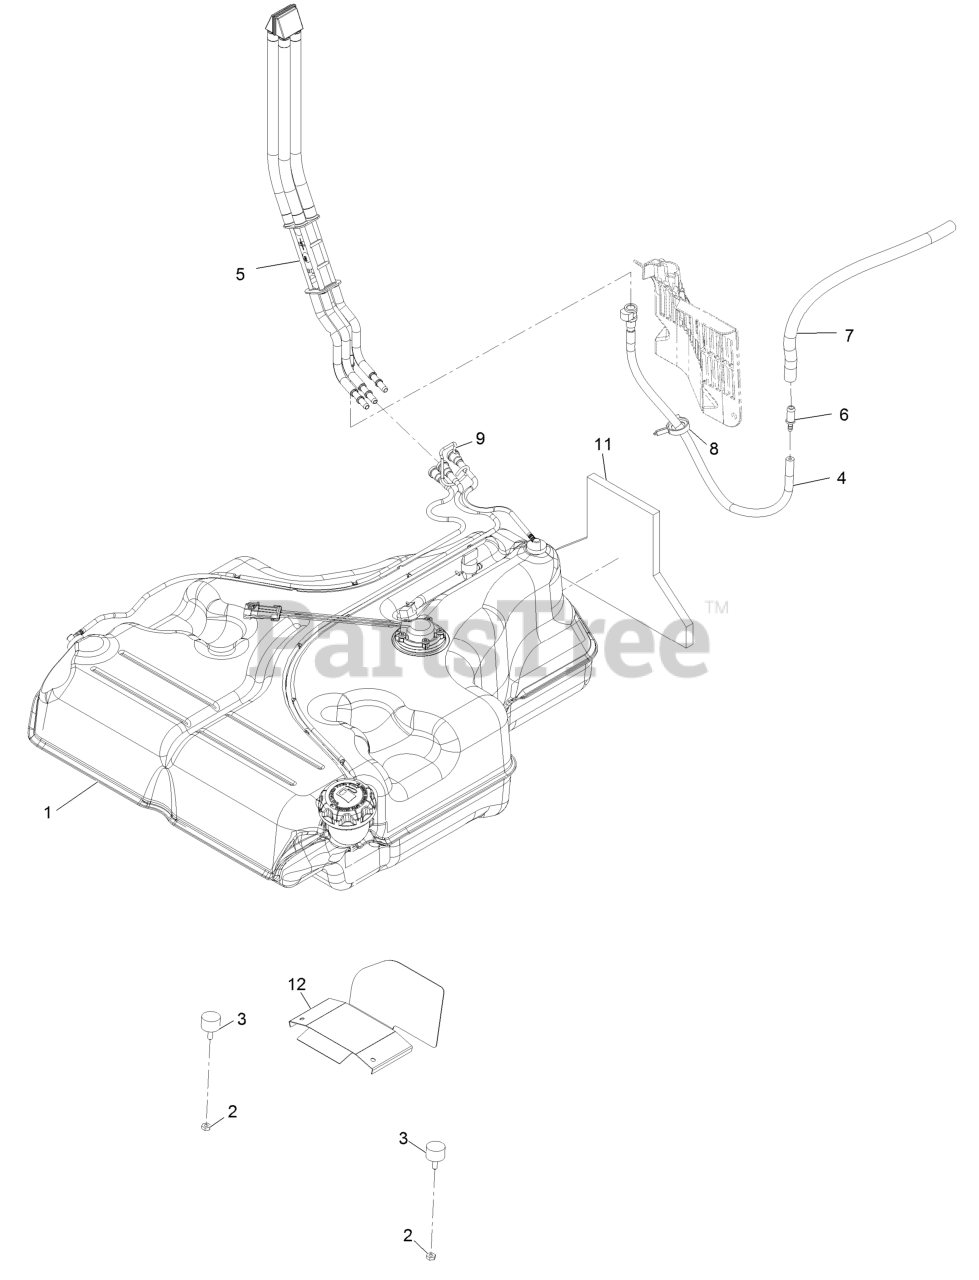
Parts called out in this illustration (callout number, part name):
2	NUT-JAM
4	HOSE ASM
5	FUEL MANIFOLD VENT ASM
6	FITTING-STRAIGHT
7	HOSE-FUEL
8	CLAMP-HOSE
9	RETAINER-LINE, VAPOR
11	INSULATION-FOAM, FUEL TAN
12	GUARD-EXHAUST
